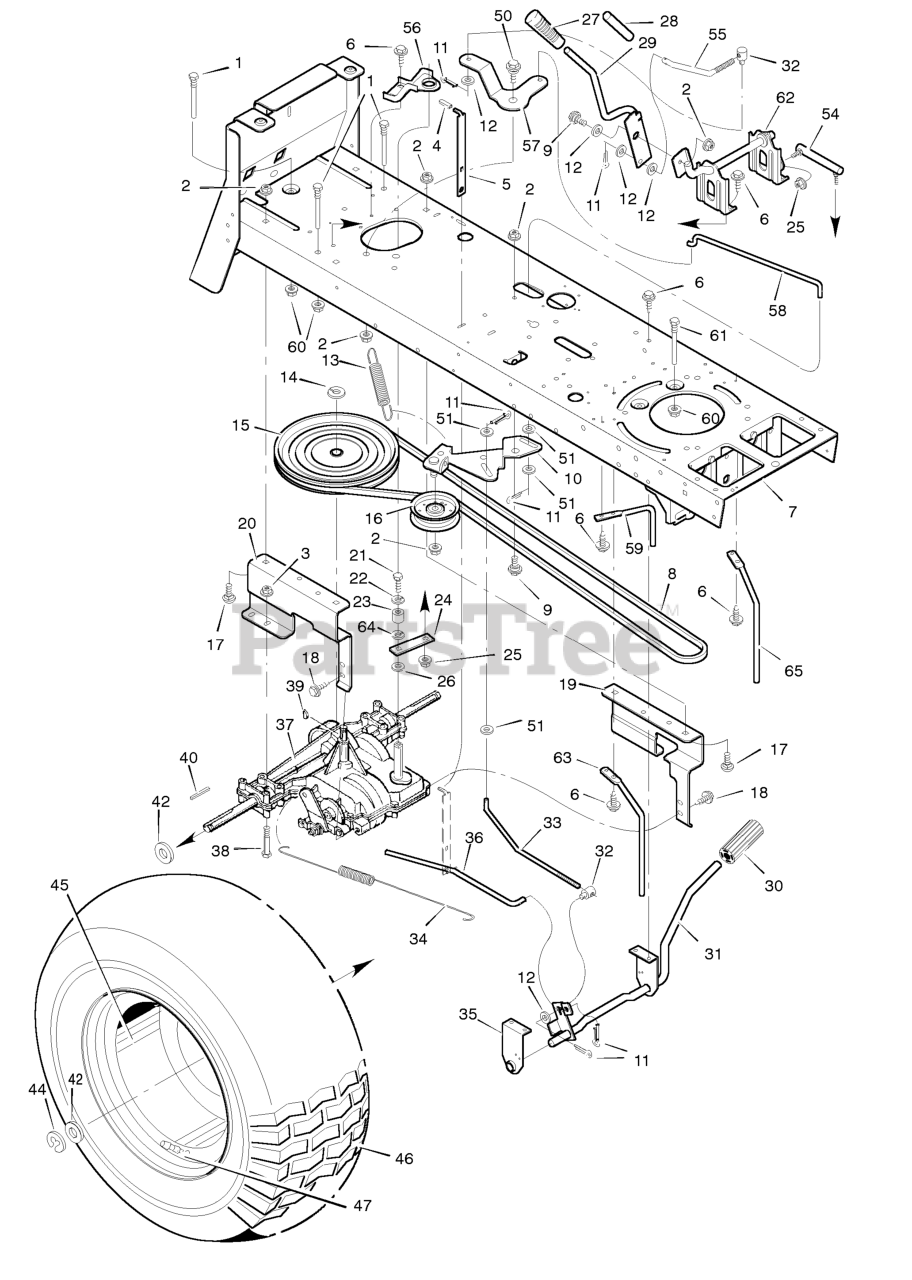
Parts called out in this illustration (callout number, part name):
1	Guide, Belt
2	Locknut, Flange
3	Locknut, Flange
5	Lever, Parking Brake
8	Belt, Motion Drive
9	Bolt, Shoulder
10	Bracket Assembly, Idler
11	Pin, Cotter
12	Washer
13	Spring, Drive Extension
14	Ring, Retainer
15	Pulley, Motion Drive
16	Pulley, Backside Idler
17	Bolt, Carriage
19	Bracket, Left Transaxle
20	Bracket, Right Transaxle
21	Bolt, Hex
22	Lockwasher
23	Pilot, Support
24	Yoke, Shift Lever
25	Locknut
27	Grip
28	Grip, Inner
29	Lever, Shift
30	Pedal, Clutch/Brake
31	Lever Assembly, Pedal
32	Nut, Adjustable
33	Rod, Clutch
34	Spring, Brake Extension
35	Bracket, Pedal Support
36	Rod, Brake Latch
37	Transaxle, Peerless **
38	Bolt, Hex
39	Key, Woodruff No. 9
40	Key, Square
42	WASHER, 1-1.3 16G FLT
45	Wheel & Tire Assembly
46	Tire Only *
47	Valve Stem
50	Bolt, Shoulder
51	Washer
52	Washer
54	Link, Shifter
55	Link, Clutch
56	Bracket, Support
57	Bracket, Pivot
58	Rod, Clutch
59	Guide, Belt
60	Nut, Flange
61	Guide, Belt
62	Shifter Assembly
63	Guide, Belt
65	Guide, Belt
